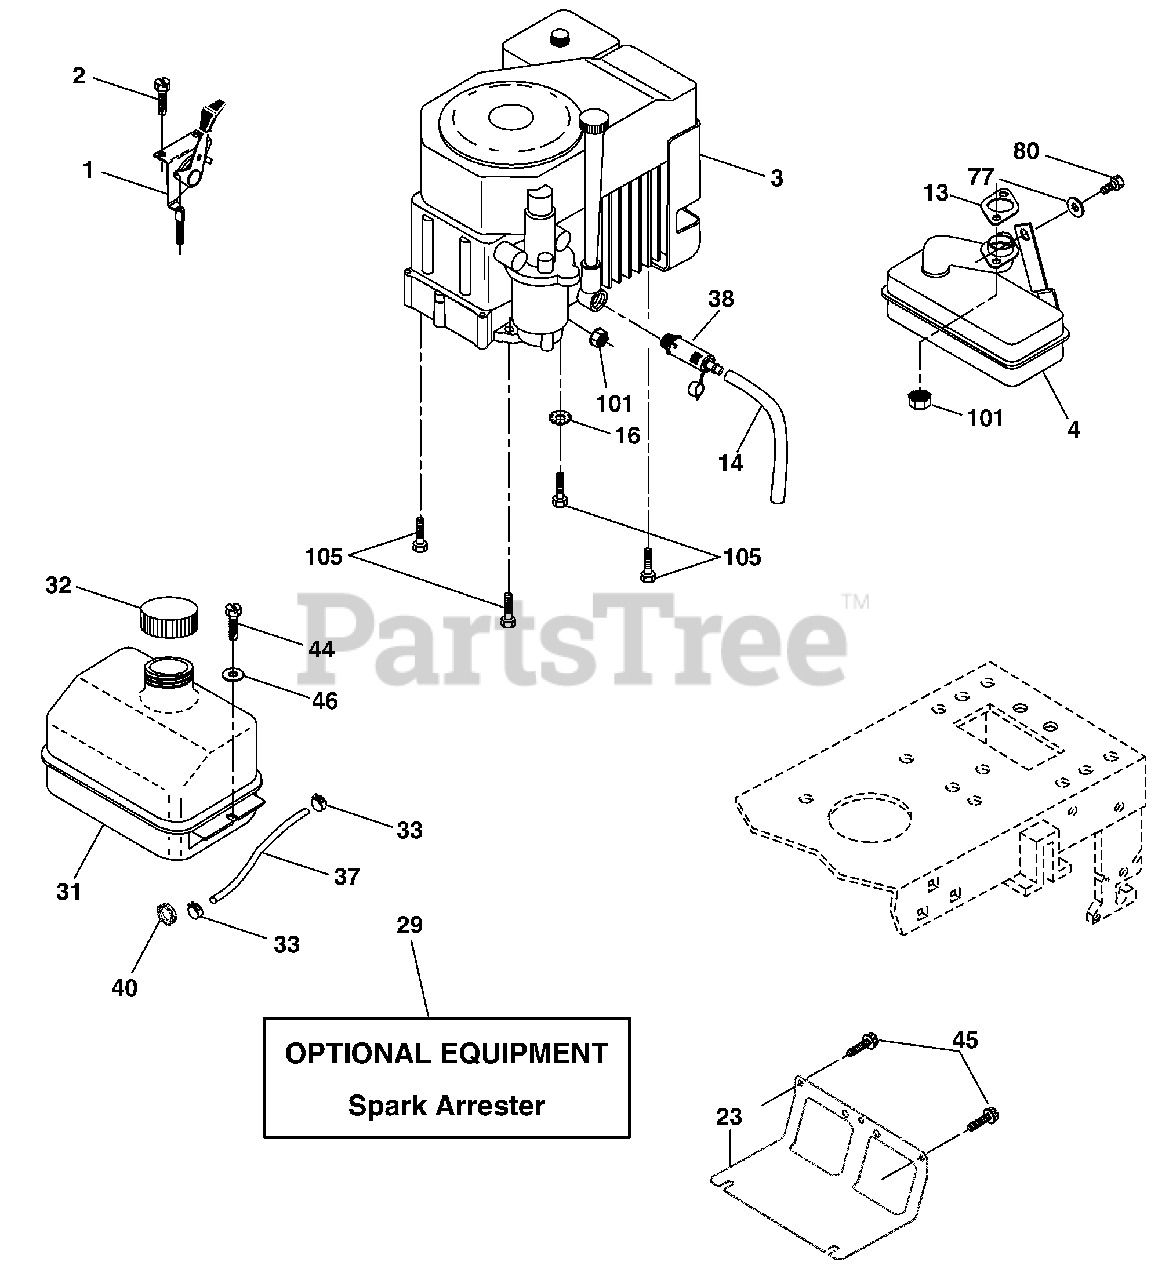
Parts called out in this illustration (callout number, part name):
1	Control Th/ch Flag
2	Screw Hex Thd Cut 1/4-20 x 1/2
13	Gasket Eng
14	Tube Drain Oil Easy
16	Washer Lock Ext Tooth 3/8
23	Shield Brn/Dbr Guard
29	Kit Spark Arrestor (Flat Scrn)
31	Tank Fuel Front
32	Cap Asm Fuel W/sym Vented
33	Clamp Hose Black
37	Line Fuel 20"
38	Plug Drain Oil Easy
40	Bushing Snap Nyl Blk Fuel Line
44	Screw Hexwsh Thdrol 1/4-20 x 3/4
45	Screw Hexwsh Thdr 3/8-16 x 3/4
46	Washer 9/32 x 7/8 x 16 Ga
77	Washer 5/16x 3/4 x 16 Ga.
80	Bolt Hex Hd 5/16-18 x 1/2
101	Nut Flange M8 1.25 N/LK Zinc
105	Screw 3/8-16 x 1
